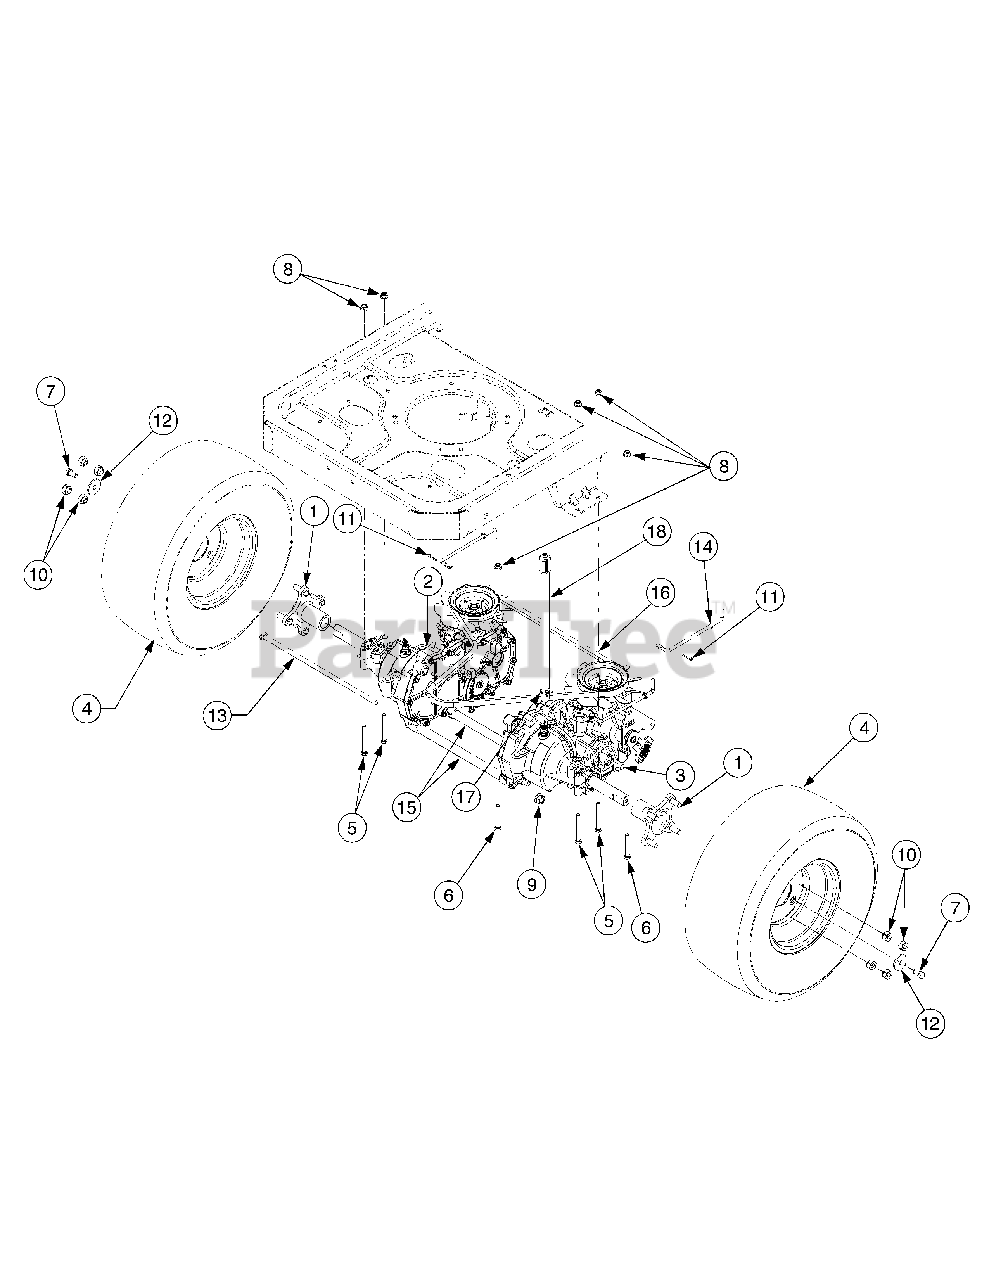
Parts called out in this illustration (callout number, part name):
1	Wheel Hub
2	Transmission Ass'y, LH
3	Transmission Ass'y, RH
5	Hex Screw 5/16-18 x 2.75
6	Hex Bolt 5/16-18 x 2.25
7	Hex Cap Lock Screw. 3/8-16 x .75 Gr. 5
8	Flange Locknut 5/16-18 Gr. F, Nylon
9	Flange Lock Nut, 7/16-20
10	Lub Nut, 7/16-14
11	Bow Tie Cotter Pin
12	Flat Washer .39 ID x 1.5 OD x .135
13	Rod, .405 x 14.0
14	Rod, Bypass
15	Tube, .45 x .69 x 10.2
16	V-Belt, Type A Sec x 57.7
